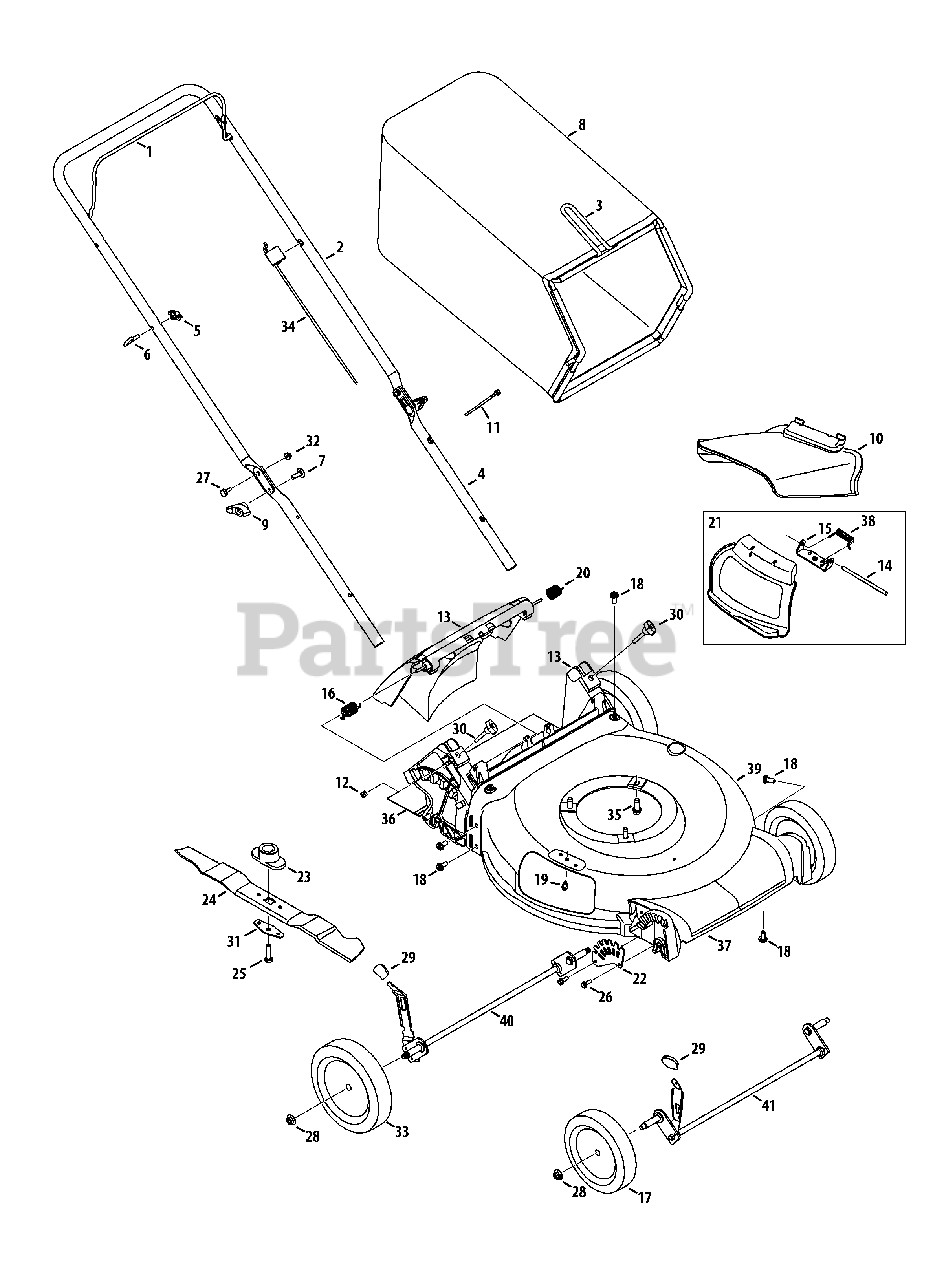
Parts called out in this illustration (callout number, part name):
1	Blade Control
2	Upper Handle, Adjustable
3	Grass Catcher Frame
4	Lower Handle
5	Wing Nut
6	Rope Guide
7	Carriage Screw, 5/16-18
8	Grass Bag, Yardman
9	Wing Knob, Black
10	Side Chute
11	Cable Tie
12	Nut, Sq., 1/4-20
13	Rear Discharge Door Assembly
14	Hinge Pin
15	Chute Deflector Bracket
16	Torsion Spring - RH
17	Front Wheel Gray
18	Screw, 5/16-14 x .750
19	Screw, 1/4-20 x .500
20	Deck , 21" - Green
21	Hinged Mulch Plug Assembly
22	Torsion Spring - LH
23	Blade Adapter, 25mm x 1.19
24	Mulching Blade
25	Screw , 3/8-24 x 1.50
26	Screw, 1/4-15 x .750
27	Sldr. Screw, .375 x .126 x 1/4-20
28	Flange Lock Nut, 3/8-16
29	Adjustment Lever Knob, Black
30	Wing Nut
31	Blade Bell Support
32	Nut, Flange Lock, 1/4-20
33	Rear Wheel Gray
34	Control Cable (139cc)
35	TT Sems Screw, 3/8-16 x 1.0
36	Trail shield
37	Front Cover
38	Torsion Spring
39	Front Height Adjuster Plate
40	Rear Axle Assembly
41	Front Axle Assembly
